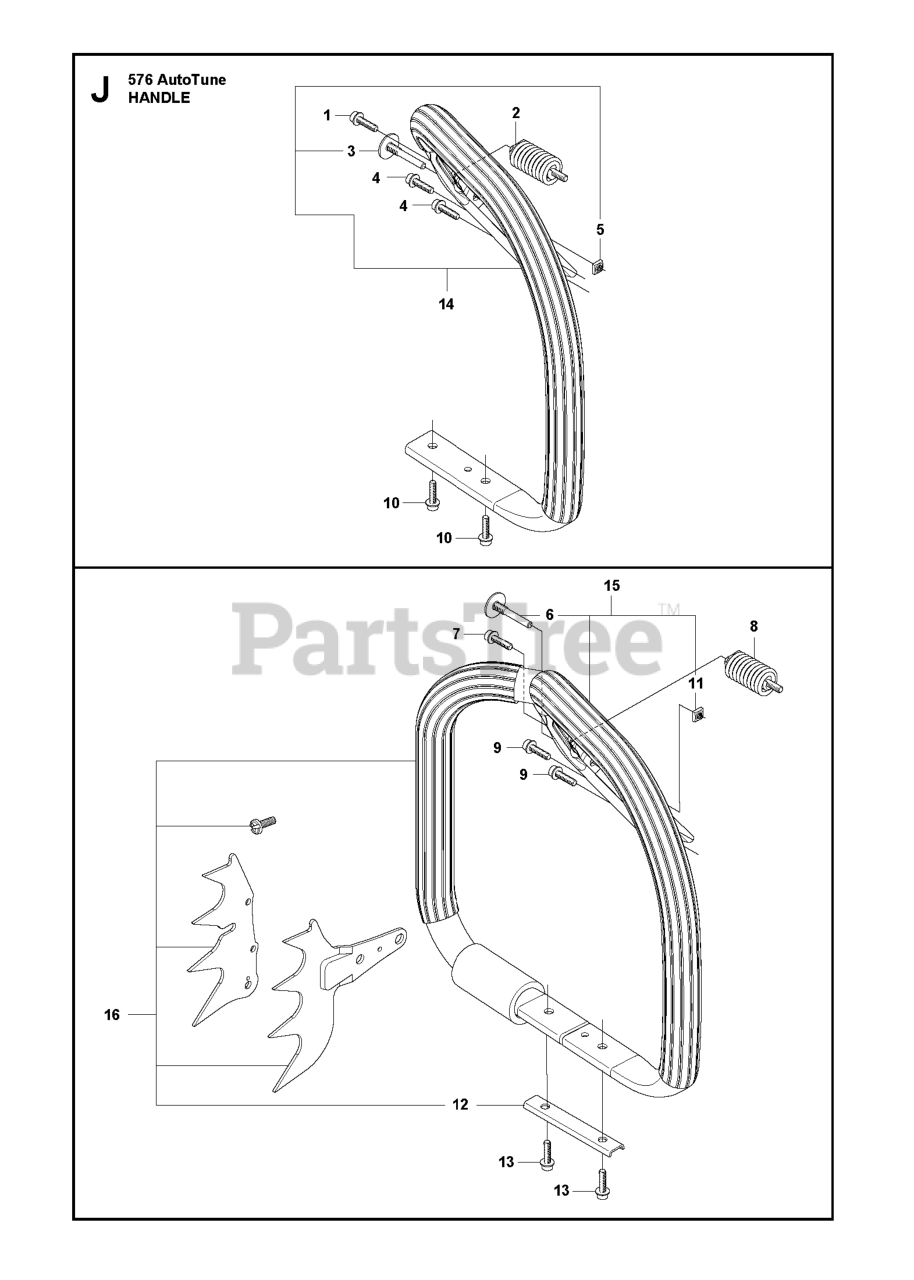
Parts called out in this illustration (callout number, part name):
2	ANTIVIBE MOUNT
8	ANTIVIBE MOUNT
14	FRONT HANDLE ASSY
15	HANDLE
16	576XP WRAP KIT
